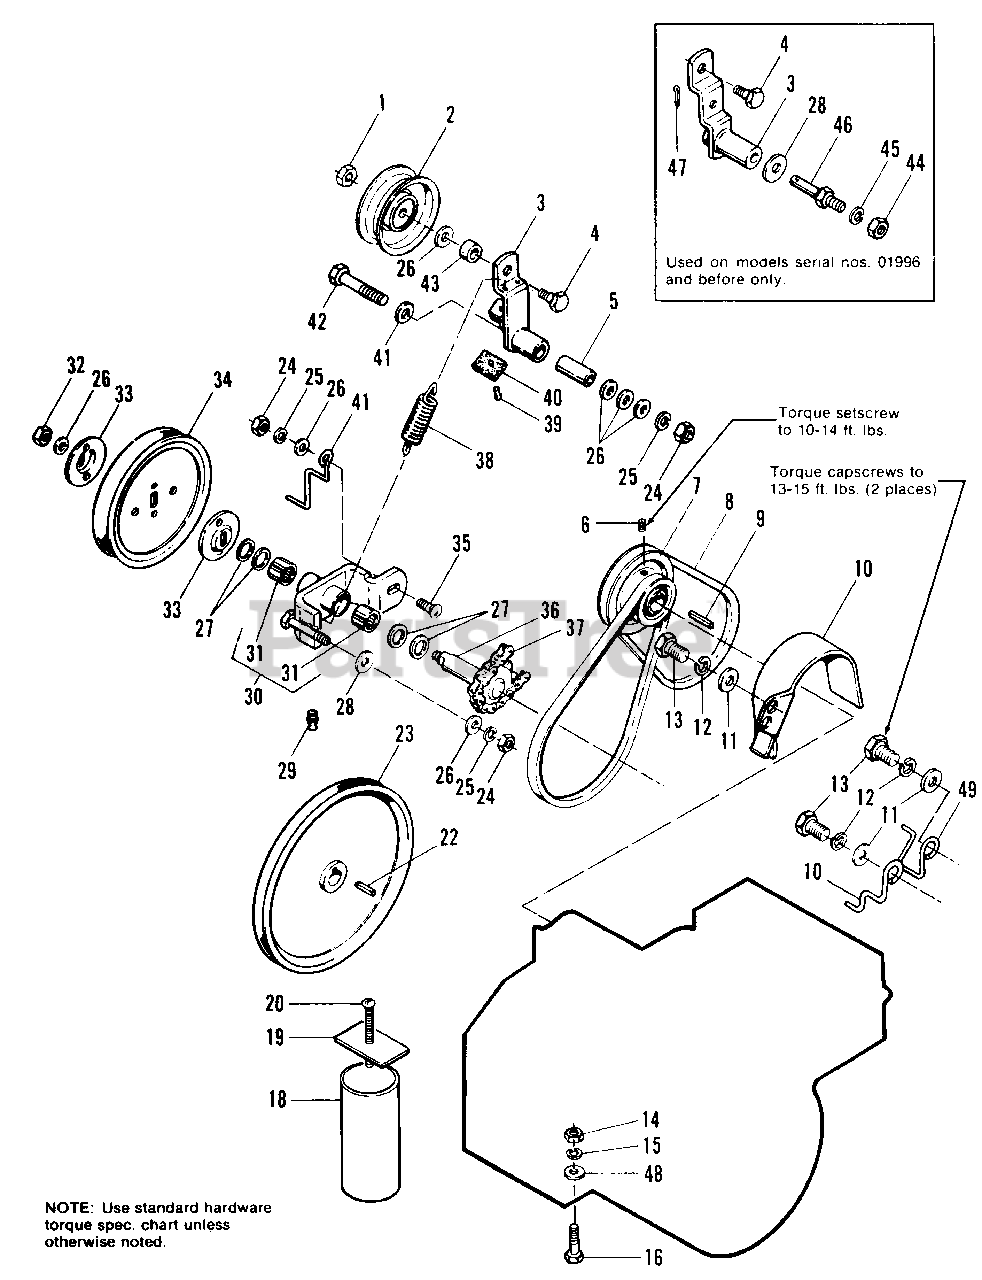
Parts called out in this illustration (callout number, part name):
1	NUT, Flange, Whizlock, 3/8-16
2	PULLEY, Idler
3	IDLER LEVER & BRAKE KIT
4	CAPSCREW, Hex Hd., 3/8-16 x 1-1/4
6	SETSCREW, 5/16-18 x 3/8
7	PULLEY, Engine
7	PULLEY, Engine (1690255 Only)
8	V-BELT, Auger Drive (1690209 Only)
8	V-BELT, 40"
8	V-BELT, Auger Drive (1690255 Only)
9	KEY (1690255 Only)
10	STOP, Belt
11	WASHER, Plain, 1/2 (1690209 & 1690255 Only)
11	WASHER, Plain, 5/16 (1690379, 1690380 & 1690442 Only)
12	LOCKWASHER, 1/2 (1690209 & 1690255 Only)
12	CAPSCREW, Hex Hd., 1/2-20 x 3/4 (1690209 & 1690255 Only)
12	CAPSCREW, Hex Hd., 5/16-24 x 3/4 (1690379, 1690380 & 1690442 Only)
14	NUT, Hex, Full, 5/16-18
15	LOCKWASHER, 5/16
16	CAPSCREW, Hex Hd., 5/16-18 x 1-1/2
16	CAPSCREW, Hex Hd., 5/16-18 x 1-3/4
16	CAPSCREW, Hex Hd., 5/16-18 x 3/4 (1690380 Only)
18	TUBE (1690209 Only)
18	TUBE (1690255 Only)
19	CLAMP (1690209 & 1690255 Only)
20	SCREW, Machine, #10-32 x 3 (1690209 & 1690255 Only)
21	V-BELT, Transmission Drive (1690209 Only)
21	V-BELT, Transmission Drive (1690379, 1690380 & 1690442 Only)
21	V-BELT, Transmission Drive (1690255 Only)
23	PULLEY, Transmission
24	NUT, Hex, Full, 3/8-16
25	LOCKWASHER, 3/8
27	WASHER, Plain, 5/16
28	SPACER, (1690379, 1690380 & 1690442 Only)
29	WASHER, Plain, 3/8 (1690209 & 1690255 Only)
30	FITTING, Grease (1690209 & 1690255 Only)
30	FITTING, Grease (1690379, 1690380 & 1690442 Only)
31	HOUSING ASSY. (1690209 & 1690255 Only)
31	HOUSING ASSY. (1690379, 1690380 & 1690442 Only)
32	BEARING, Roller
33	LOCKNUT, Jam, 3/8-16 (1690209 & 1690255 Only)
34	WASHER, Special
35	PULLEY (Use after 01688) (1690255 Only)
35	PULLEY (Use before 01689) (1690255 Only)
36	BOLT, Carriage, 3/8-16 x 1-1/4
37	SHAFT ASSY.
40	RIVET, #7 x 3/8 (Brass)
41	PAD, Brake
42	STOP, Belt
43	CAPSCREW, Hex hd., 3/8-16 x 2-1/2
45	NUT, Hex, Full, 7/16-14 (1690209 & 1690255 Only)
46	LOCKWASHER, 7/16 (1690209 & 1690255 Only)
47	STUD (1690209 & 1690255 Only)
48	PIN, Cotter, 1/8 x 3/4 (1690209 & 1690255 Only)
49	WASHER, Plain, Special, 5/16 (1690379, 1690380 & 1690442 Only)
50	STOP, Belt (1690379, 1690380 & 1690442 Only)
51	STOP, Belt (1690379, 1690380 & 1690442 Only)
